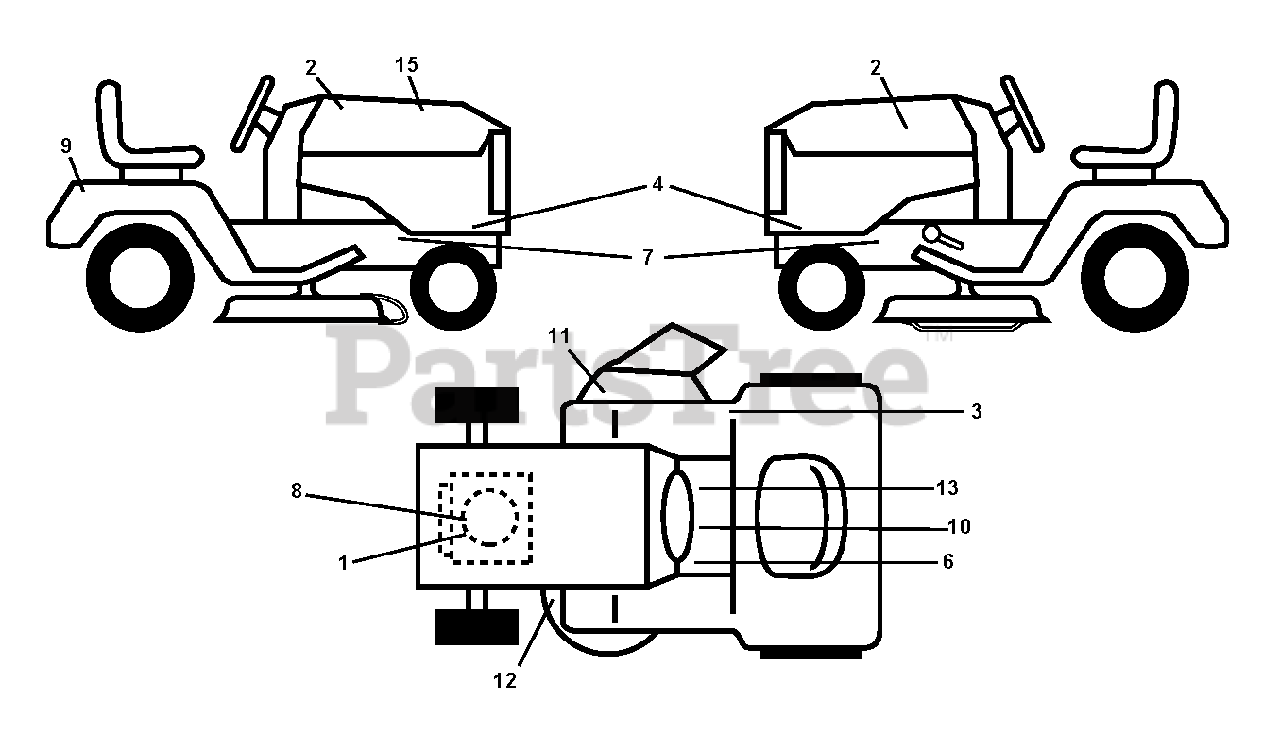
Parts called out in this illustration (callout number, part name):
1	DECAL
2	RP.DECAL.BADGE.170MM.TEXTLOGO
3	Decal, Fender 100 DB/CE
6	DECAL
8	DECAL
9	DECAL BTRY SYMBOLS
10	LABEL
11	DECAL.WARN.DFLECT/CTFINGR.SRD
12	Decal, Mower V-Belt Schematic
13	DECAL PARK BRAKE
15	DECAL DECAL.RPL.BSM21.PB.SRD.3
